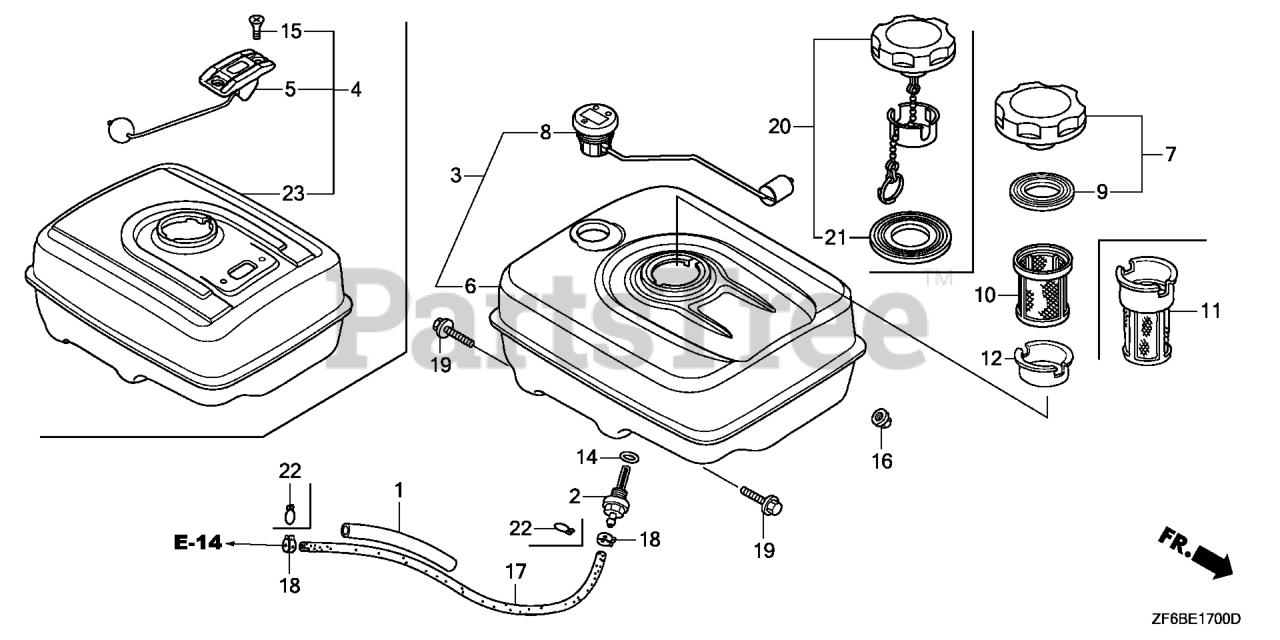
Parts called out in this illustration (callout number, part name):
1	RUBBER, SUPPORTER (107MM)
2	JOINT, FUEL TANK
6	TANK, FUEL *NH1* (BLACK)
6	TANK, FUEL *NH31* (MCKINLEY WHITE)
14	O-RING (14MM) (ARAI) Use up to Engine SN 2949254.
16	NUT, FLANGE (8MM)
17	TUBE, FUEL (4.5X235) (FKM)
19	BOLT, FLANGE (8X25)
20	CAP, FUEL FILLER
21	GASKET, FUEL FILLER CAP
22	CLIP, TUBE (D8)
